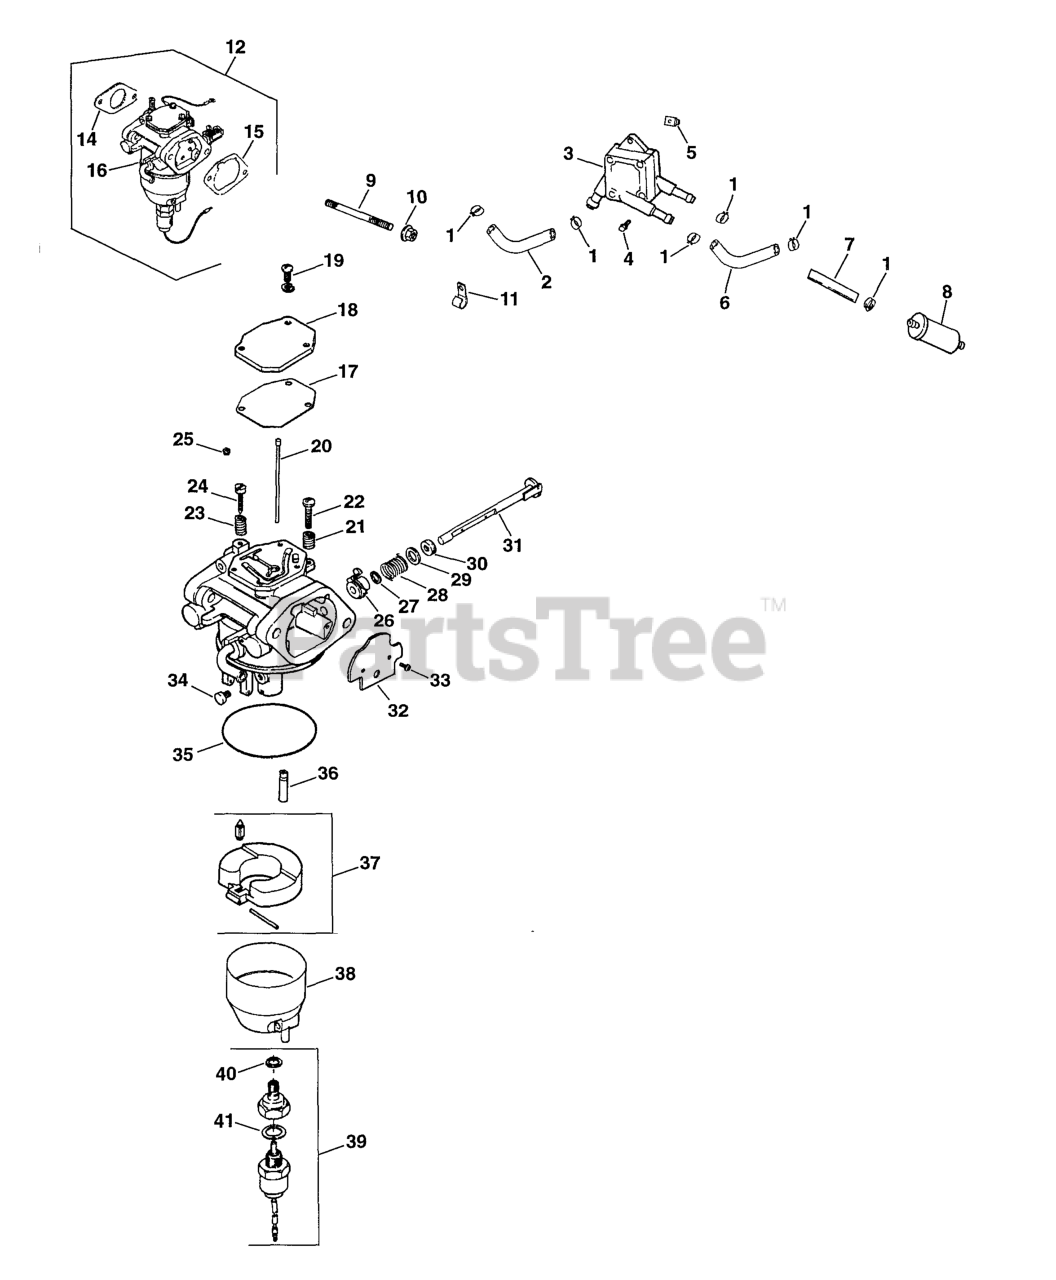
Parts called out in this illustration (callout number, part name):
2	Line, Fuel 11-1/2"
3	Pump, Fuel - Pulse
4	Screw, Hex. Cap 18 Mm
6	Line, Fuel 10-5/8"
9	Stud, M6x1.0x128
10	Nut, Hex. M6x1.0
14	Gasket, Carburetor
15	Gasket, Air Cleaner Base
16	Carburetor Assembly
17	Gasket, Passage Cover
18	Cover, Passage
19	Screw, Sems Pan Hd. M4x0.7x8
20	Jet, Slow
21	Spring, Idle Adjusting Screw
22	Screw, Idle Adjusting
23	Spring, Throttle Adjusting Screw
24	Screw, Throttle Adjusting
25	Jet, Air Bleed
26	Lever, Choke
27	Ring, Choke Lever
28	Spring, Choke Return
29	Collar, Choke
30	Washer, Felt 5.7 Mm
31	Shaft, Choke
32	Plate, Choke
33	Screw, Sems Pan Hd. M3x0.5x4.5
34	Jet, Main
35	Gasket, Float Chamber
36	Nozzle, Main
37	Kit, Float
38	Chamber, Float (Bowl)
39	Kit, Solenoid Valve
40	Gasket, Chamber Screw
41	Gasket, Solenoid
